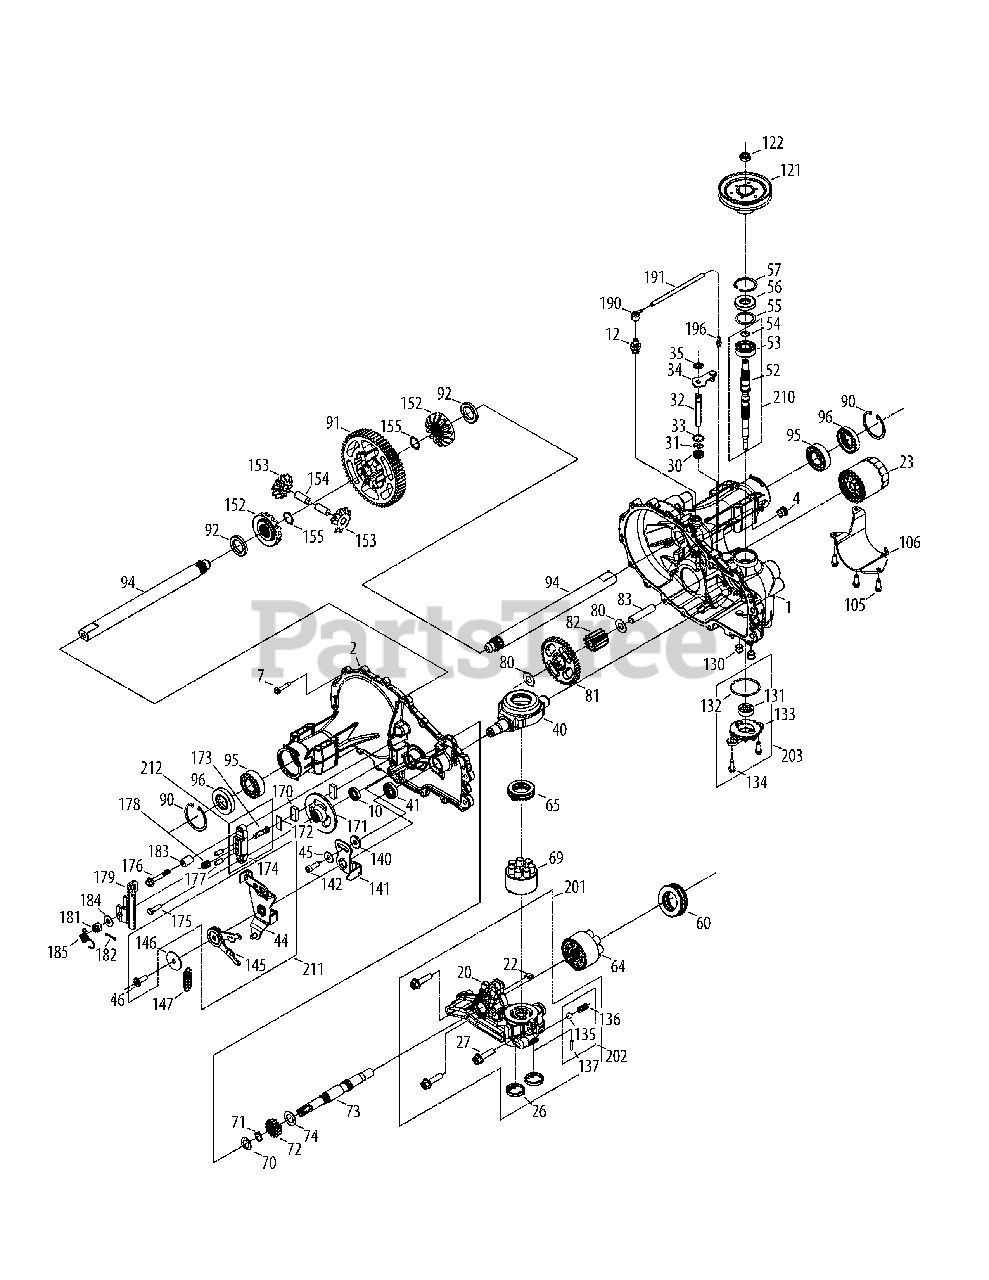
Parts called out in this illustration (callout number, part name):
1	Kit, Housing, Main
1	Housing, Main
1	Pin, Standard Headless
1	Bushing, .624 x .719 x .562
1	Bushing, .865 x .985 x .790
1	Bearing, Flange 1.0 x 1.376 x .99
2	Kit, Housing, Side
2	Housing, Side
2	Bushing, .624 x .729 x .562
2	Bushing, .865 x .985 x .790
2	Bearing, Flange 1.0 x 1.376 x .99
4	Plug, 9/16-18 (Metal)
006	Pin, Standard Headless
7	HFHCS 1/4-20 x 1.25
10	Seal, Lip .625 x 1.0
010	Seal, Lip .625 x 1.0
12	Assembly, Fitting, Metal
020	Center Section, LH, CHRG
22	Plate, Bypass
022	Plate, Bypass
23	Filter, Oil
024	Check Plug
025	Check Plug
26	Seal, Plug 1.250 x .250
026	Seal, Plug 1.250 x .250
27	HFHCS 3/8-16 x 1.5 (Patch)
027	HFHCS 3/8-16 x 1.5 (Patch)
30	Seal, Lip .375 x .75 x .25
030	Seal, Lip .375 x .75 x .25
31	Ring, Retaining .375 External
031	Ring, Ret .375 External
32	Rod, Bypass
33	Ring, Retaining .750 Internal
033	Ring, Ret .750 Internal
34	Arm, Bypass
35	Ring, Retaining .375 Internal
035	Ring, Ret .375 External
40	Trunnion, Swashplate
41	Seal, Lip 18 x 32 x 7
041	Seal, Lip 18 x 32 x 7
044	Arm, Control
45	Washer, .24 x .88 x .05
46	TWHCS 5.16-24 x 1.00 (Patch)
046	TWHCS 5.16-24 x 1.00 (Patch)
046	Screw 5/16-24 x 1.00 (Patch)
052	Shaft, Input
053	Brg, Ball 17 x 40 x 12 Open 6203
054	Ring, Ret Wire .561 ID
55	Washer, 1.23 x 1.56 x .04
56	Seal, Lip 17 x 40 x 17
056	Seal, Lip 17 x 40 x 7
57	Ring, Retaining 1.575 Internal
057	Ring, Ret 1.575 Internal
60	Bearing, Thrust
64	Assembly, Cylinder Block, 16cc
65	Bearing, Thrust Ball 30 x 52 x 13
69	Assembly, Block 7 Piston
70	Washer, .63 x 1.0 x .05
71	Ring, Retaining .625 External
071	Ring, Ret .625 x External
72	Gear, 14T
73	Shaft, Motor
74	Washer, .72 x 1.16 x .04
80	Washer, .5 x 1.0 x .03
81	Gear, 45T
82	Gear, 11T
83	Pin, Jackshaft
90	Ring, Retaining 2.06 Internal
090	Ring, Ret .206 Internal
91	Gear, 60T
92	Spacer, 1.04 x 1.65 x .22
94	Shaft, Axle 1.00 x 13.37, DD
95	Bearing, Ball 1.0 x 52 x 15
96	Seal, Lip 25 x 52 x 10 TC (Gray)
096	Seal, Lip 25 x 52 x 10 TC (Gray)
105	HFHCS 1/4-20 x .75
106	Guard, Filter, LH
121	Pulley, 4.0"
122	Hex Lock Nut 1/2-20 (Nylon Insert)
123	Screw Hex 1/4-20 x .875
130	Tube, Connecting
131	Gerorter Assembly (1.9cc/REV)
132	O-Ring - 137, .103 x 2.050
133	Cover, Charge Pump
134	Screw, Pan Head 1/4-20 x .75
135	Ball, Steel 7/16"
136	Spring, Relief .42 x .75
137	Pin, Spring .125 x .875
140	Spacer, .320 x 1.005 x .179
141	Assembly, RTN, Neutral Arm
142	SHCS 5/16-24 x 1 Patch
145	Assembly, RTN Bidirectional
146	Washer, .343 x 1.500 x .062
147	Spring, Extension RTN - 44 LBS
152	Gear, Bevel 14T Spline ID
153	Gear, Bevel 10T
154	Pin, .499 x 1.20
155	Ring, Spiral Retaining - 87
155	Ring, Sprial Ret .875
170	Puck, Brake
171	Rotor, Brake
172	Plate, Puck
173	Bolt, Square Head
174	Brake Yoke
175	Bolt, Hex Head 1/4-20 x 1 w/ Patch
176	Bolt, Hex Head 1/4-20 x 2 w/ Patch
177	Pin, Brk .31 x .73 Plated
178	Spring, Comp Brake Anti-Drag
179	Arm, Brake
181	Nut, Castle 5/16-24 PL
182	Pin, Cotter 3/32 x 3/4
183	Spacer, .26 x .57 x .87
184	Washer, .27 x .88 x .12
185	Spring, Brake Arm Bias
190	Cap, Barbed
191	Hose, .28 x .15 x 10.00
196	Fitting, Barbed
201	Kit, Center Section, LH, CHRG
202	Kit, Charge Relief
203	Kit, Charge
210	Kit, Input Shaft
211	Kit, RTN Bidirectional
212	Kit, Brake-Yoke
